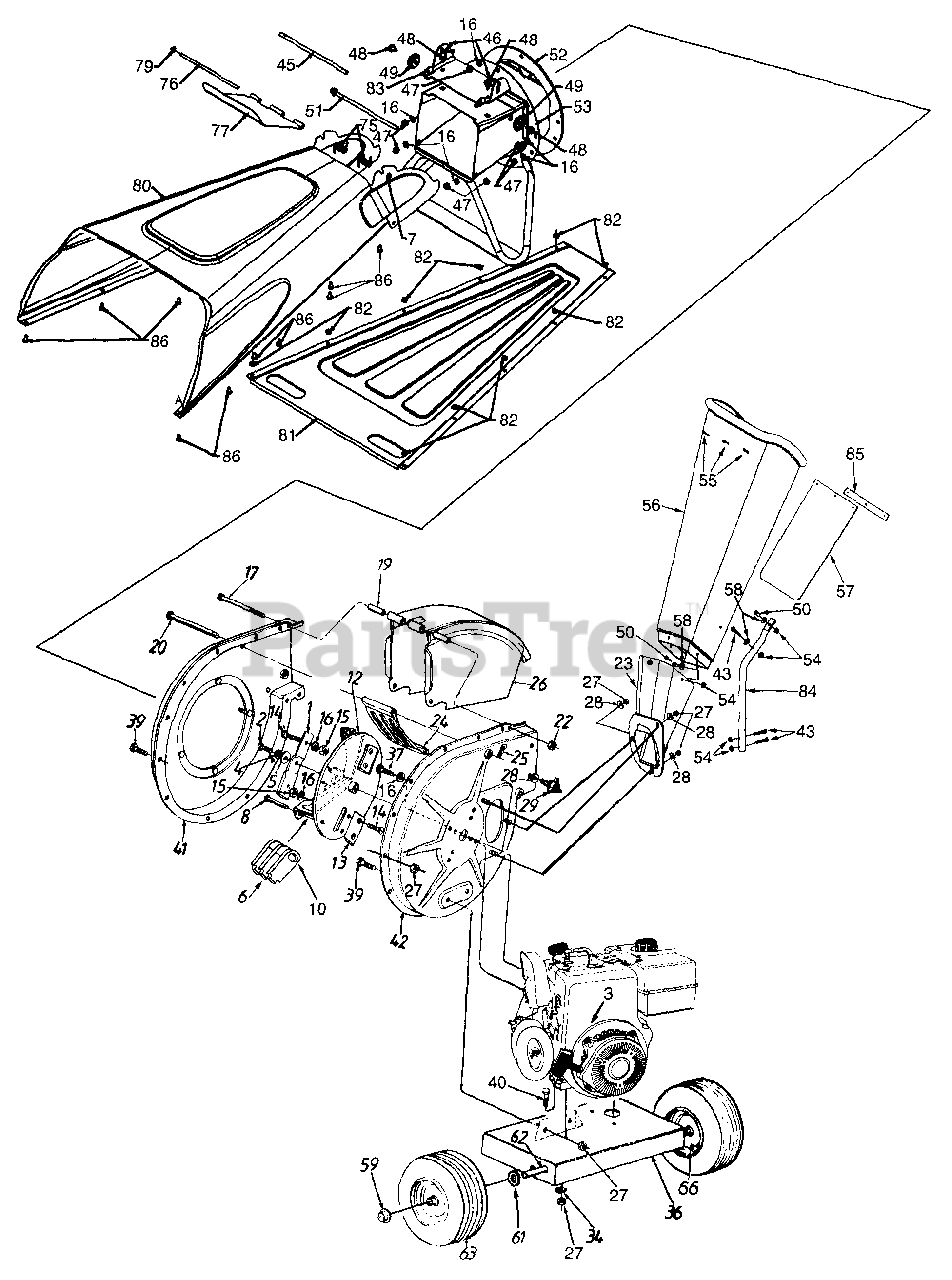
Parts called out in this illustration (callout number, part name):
1	Shredder Blade
2	Hex Patch Bolt 3/8-24 x 2.25" Lg. (Gr. 8)
3	Engine
4	Lock Washer 3/8" I.D.
5	Flat Washer .406" I.D. x 1.25" O.D.
6	Flail Blade
8	Clevis Pin .496" dia.
10	Spring Roll Pin 1.12" Lg.
12	Impeller Ass'y. Comp.
13	Chipper Blade
14	Flat Hd. Scr. 5/16-24 x .75" Lg.
15	Hex Top Lock Nut 5/16-24 (Gr. 5)
16	Lock Washer 5/16" I.D.
17	Hex Bolt 1/4-20 x 3.75" Lg.
19	Chute Hinge Spacer 1.66" Lg.
20	Clevis Pin .5" Dia. x 4.62" Lg.
22	Hex Ctr. Lock Nut 1/4-20 Thd.
25	Internal Cotter Pin 3/8" dia.
27	Hex Nut 5/16-18 Thd. (Gr. 5)
28	Bell Washer .345" I.D. x .88"
29	Hand Knob
34	Spec. Lock Washer 5/16" I.D.
37	Hex Bolt 5/16-24 x .75" Lg.
39	Hex Bolt 5/16-18 x .75" (Gr. 5)
40	Hex Bolt 5/16-18 x 1.5"
43	Hex Scr. 1/4-20 x .625 (Gr. 2)
45	Release Bar
46	Torsion Spring
47	Elastic Lock Nut 5/16-18 Thd.
48	Hex Washer Hd. Self-Tapping Scr. 5/16-18 x .50" Lg.
49	Stop Washer
50	Hex Bolt 1/4-20 x .625
51	Hex Bolt 5/16-18 x 8.38" Lg.
55	Pop Rivet
56	Chipper Chute
57	Shredder Chute Flap
58	Flat Washer .28 I.D. x .74 O.D.
59	Push Cap 5/8" Dia. Rod
61	Flat Washer 1.12 O.D. x .64 I.D. x .120
62	Shredder Axle
63	Wheel Ass'y. Comp.
66	Air Valve
75	Torsion Spring
76	Hopper Door Rod
85	Flap Strip
86	Screw 1/4" - 20 .5in.
